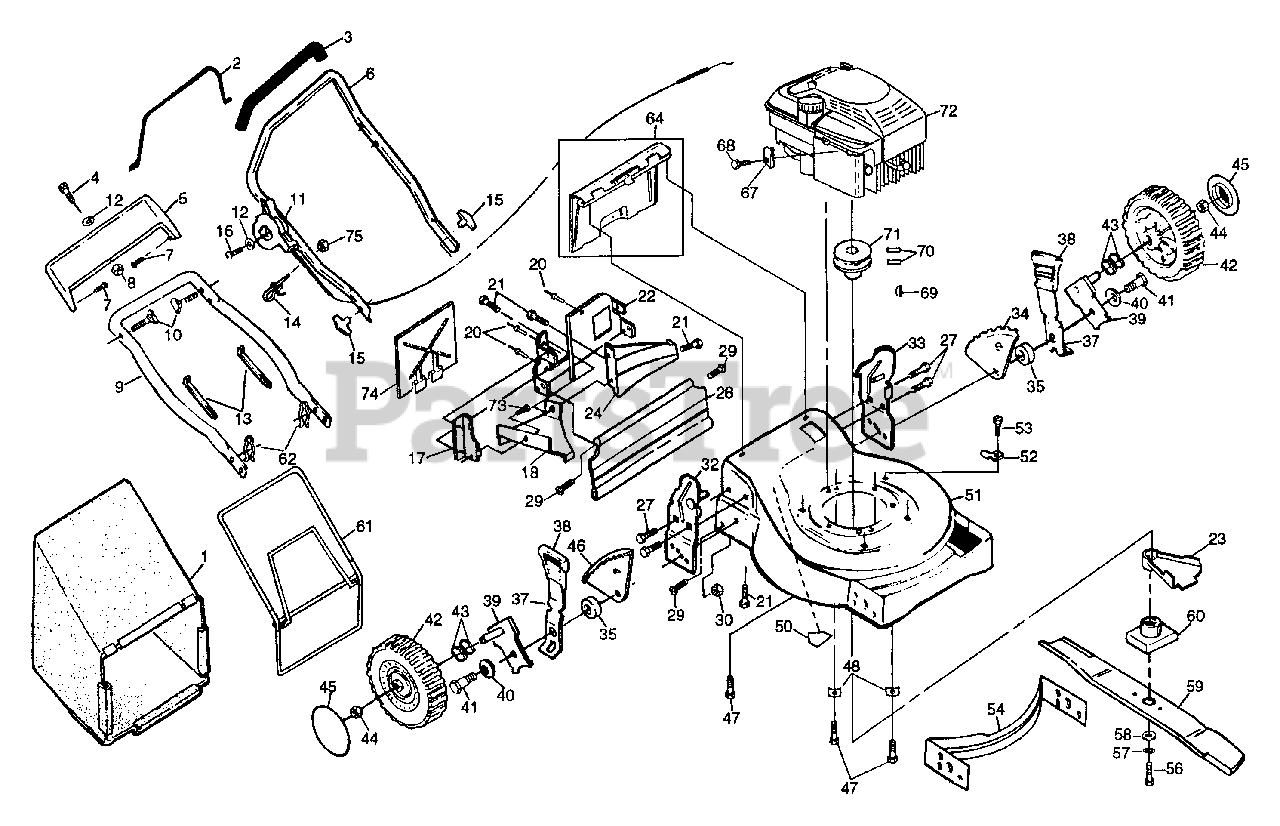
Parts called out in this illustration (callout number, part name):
1	Grass Bag Assembly
2	Control Bar
3	Handle Grip
4	Hex Washer Head Machine Screw 1/4-20 x 1-1/2
5	Trim Plate
6	Upper Handle
7	Self-tapping Screw #10-24 x 5/8
8	Locknut 1/4-20
9	Lower Handle
10	Handle Bolt
11	Throttle Control
13	Wire Tie
14	Rope Guide
15	Handle Knob
16	Round Head Screw 1/4-20 x 2-3/4
17	Side Baffle
18	Discharge Baffle
21	Hex Tapping Screw 1/4-20 x 1/2
22	Back Plate
23	Debris Shield
24	Rear Baffle
26	Rear Skirt
27	Thread Cutting Screw 5/16-18 x 3/4
29	Hinge Screw
30	Locknut
32	Handle Bracket Assembly (Right)
33	Handle Bracket Assembly (Left)
34	Wheel Adjusting Bracket (LR)
35	Spacer
37	Selector Spring
38	Selector Knob
39	Axle Arm Assembly
40	Belleville Washer
41	Shoulder Bolt 3/8-16
42	Wheel & Tire Assembly
43	Wave Washer
44	Nut
46	Wheel Adjusting Bracket (RR)
47	Thread Rolling Screw 3/8-16 x 1
48	Engine Washer
50	Danger Decal
51	Lawn Mower Housing
52	Guide Clip (Housing)
53	Hex Washer Head Screw #10-24 x 1/2
54	Front Baffle
56	Hex Head Screw 3/8-24 x 1-3/8 Gr. 8
57	Helical Lockwasher 3/8
58	Hardened Washer
60	Blade Adapter
61	Catcher Frame Assembly
62	Hairpin Cotter
64	Rear Door Assembly
67	Cable Clamp
68	Thread Rolling Screw #10-32 x 5/8
69	Hi-Pro Key
70	Set Screw 1/4-20 x 5/16
71	Engine Pulley
72	Engine
74	Mulcher Plate
75	Keps Locknut
